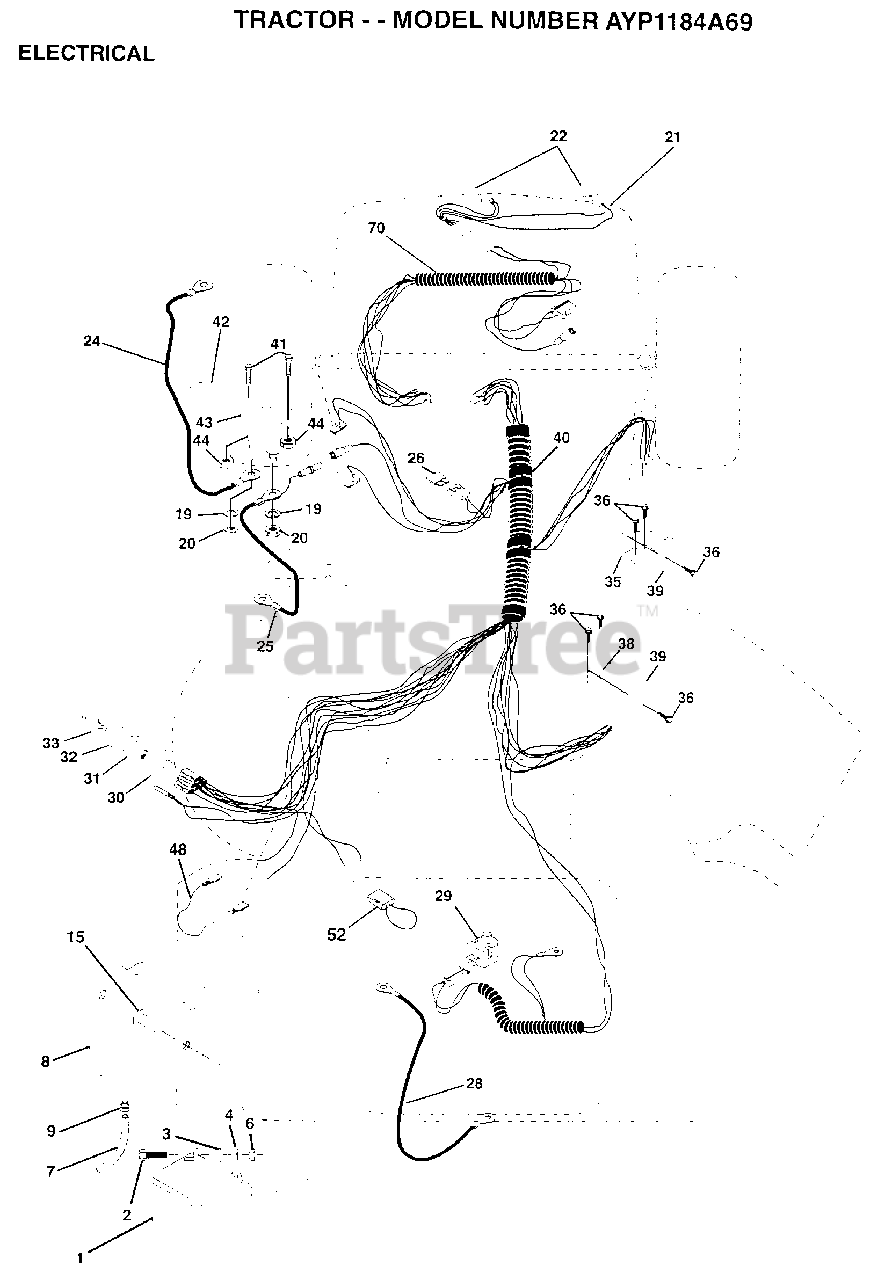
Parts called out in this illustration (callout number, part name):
2	BOLT LT
3	WASHER
4	LOCKWASHER
7	TUBE T
9	HOSE CLAMP T
15	FASTNER.SNAP-IN
20	NUT
21	"HARNESS,LIGHT SOC"
22	HEADLAMP BULB
24	CABLE-BATTERY T
25	CABLE.BTRY.6GA.RD
26	FUSE HYT
28	CABLE T
29	SWITCH SEAT
30	SWITCH IGN 4POS
31	NUT IGNITION
32	COVER KEY SWITCH
33	KEY
35	BRACKET LT
36	SCREW
38	BRACKET SWITCH IN
39	SWITCH INTERLOCKT
40	HARNESS.IGNITION
44	NUT HXKEP 1/4X20
48	ADAPTER AMMETER
52	PROTECTION LOOP
70	HARNESS.ENG.LT.
471	BOLT HXHD FIN
